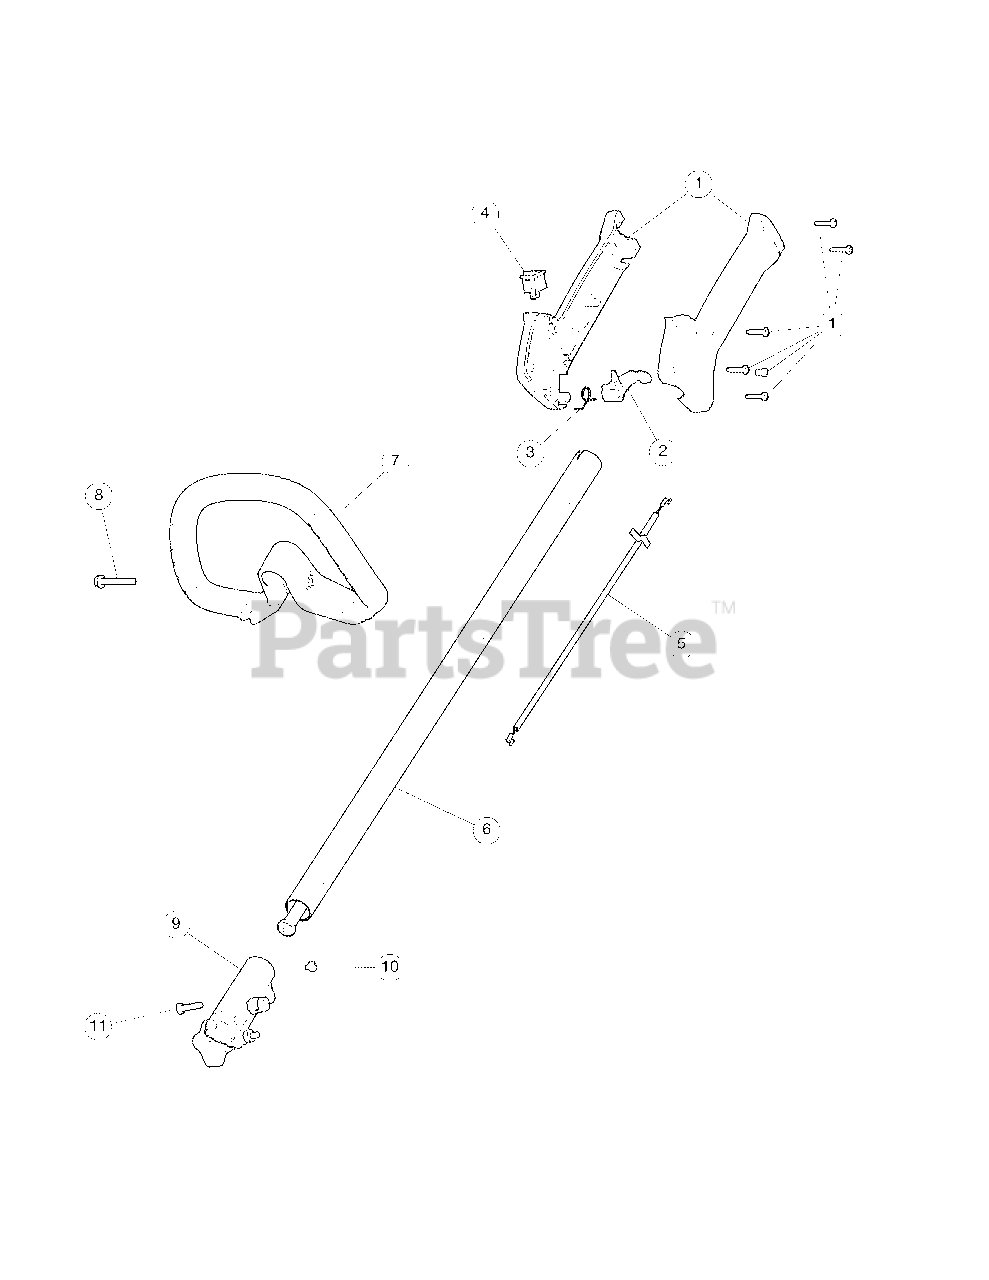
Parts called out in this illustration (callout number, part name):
1	Throttle Housing Assembly (Incl. 2-4)
2	Throttle Trigger
3	Throttle Trigger Spring
4	Switch Assembly
5	Throttle Cable Assembly
6	Upper Drive Shaft Assembly
7	D-Handle Assembly (Incl. 8)
9	Split Boom Coupler (Incl. 10-11)
10	Coupler Anti-Rotation Screw
11	Coupler Hardware
